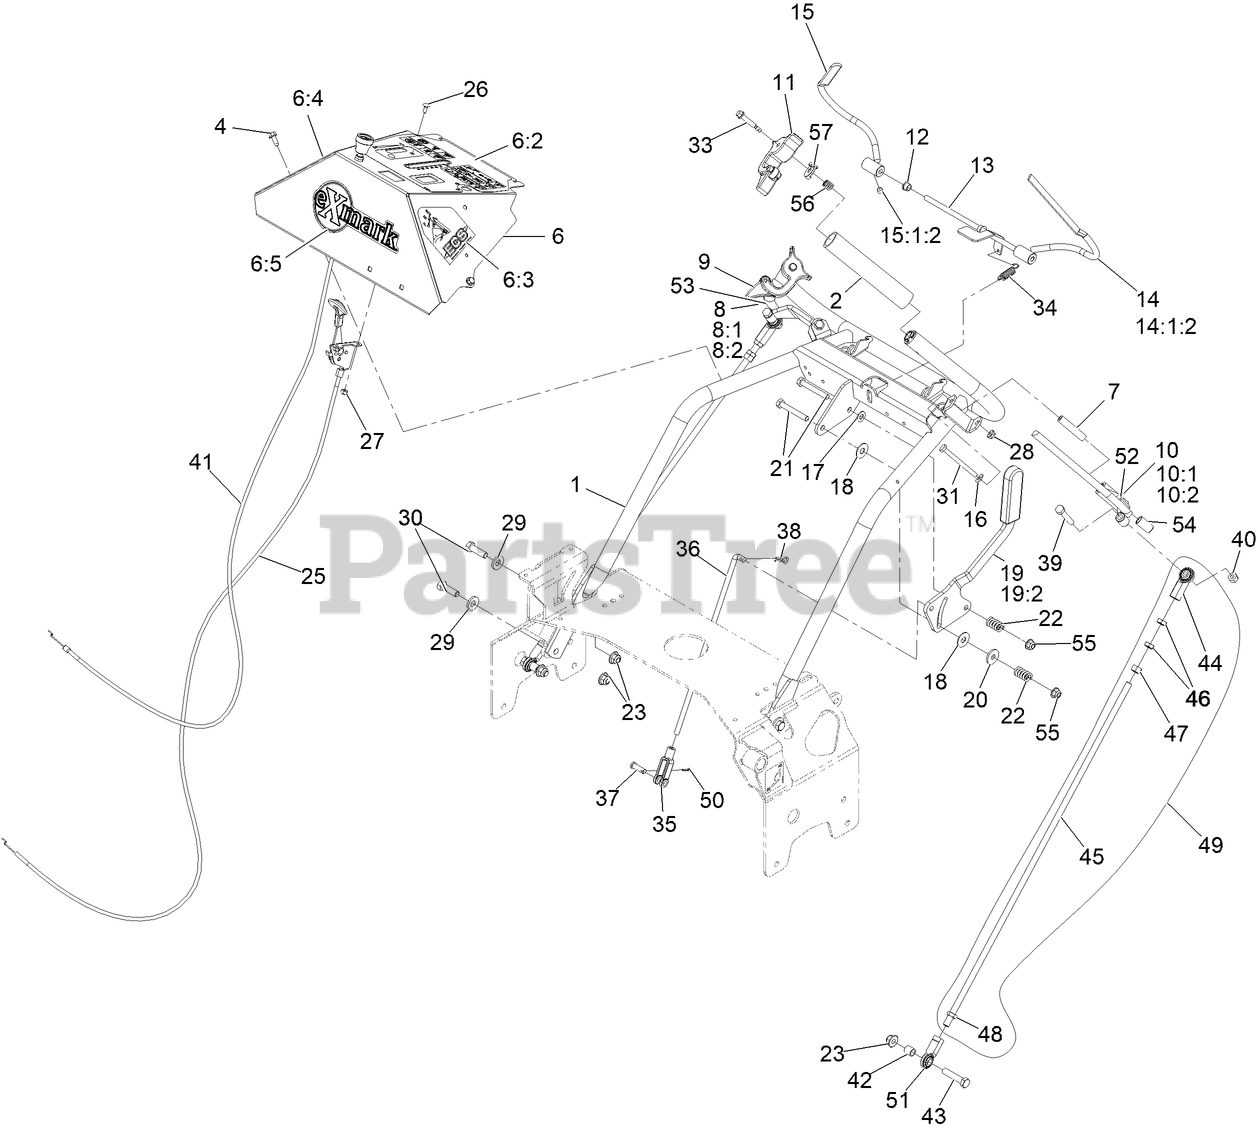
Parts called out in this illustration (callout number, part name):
1	WELD, HANDLE
2	GRIP-BAR, HANDLE
4	SCREW-HWH
6	ASM, CONSOLE W/ DECALS
6:2	DECAL-CONSOLE
6:3	DECAL,LH ECS INSTRUCTION
6:4	DECAL,RH ECS INSTRUCTION
6:5	DECAL, EXMARK LOGO
7	BUSHING-LEVER, DRIVE
8	DRIVE LEVER-ASM, RH
8:1	WLD,RH DRIVE LEVER
8:2	BUSHING, SLEEVE
9	ASM,LATCH RH THUMB
10	DRIVE LEVER-ASM, LH
10:1	WLD,LH DRIVE LEVER
10:2	BUSHING, SLEEVE
11	ASM,LATCH LH THUMB
12	BUSHING-NYLON
13	WLD,OPC LEVER AXLE
14	WLD,LH OPC LEVER
14:1:2	SCREW-SET
15	WLD,RH OPC LEVER
15:1:2	SCREW-SET
16	WASHER-FLAT
17	WASHER-PLAIN
19	LEVER, SHIFT W/GRIP
19:2	GRIP-HANDLE, STEERING
20	WASHER-FRICTION
21	SCREW-HH
22	SPRING-COMPRESSION
23	NUT-HF, NI
25	CONTROL-THROTTLE
26	BOLT-CARR
27	NUT-LOCK, NI
29	WASHER-BELLEVILLE
30	SCREW-HH
31	SCREW-HH
33	SCREW-SHOULDER
34	SPRING-EXTENSION
35	YOKE-ADJUSTABLE
36	ROD,SPEED CONTROL
37	PIN-CLEVIS
38	PIN-COTTER
39	SCREW-HH
40	NUT-LOCK, NI
41	CABLE, CHOKE
42	SPACER-TUBE, PUMP LINK
43	SCREW-HH
44	JOINT-BALL, END
45	LINK,DRIVE (PLTD)
46	NUT-HJ
47	NUT-HEX
48	NUT-HEX JAM, LH
49	DRIVE LINK ASM
50	PIN-COTTER
51	JOINT-BALL END, LH
52	WLD,LH DRIVE LEVER
53	WLD,RH DRIVE LEVER
54	BUSHING, SLEEVE
55	NUT-HF, NI
56	SPRING-TANK, FUEL
57	LATCH, ECS
